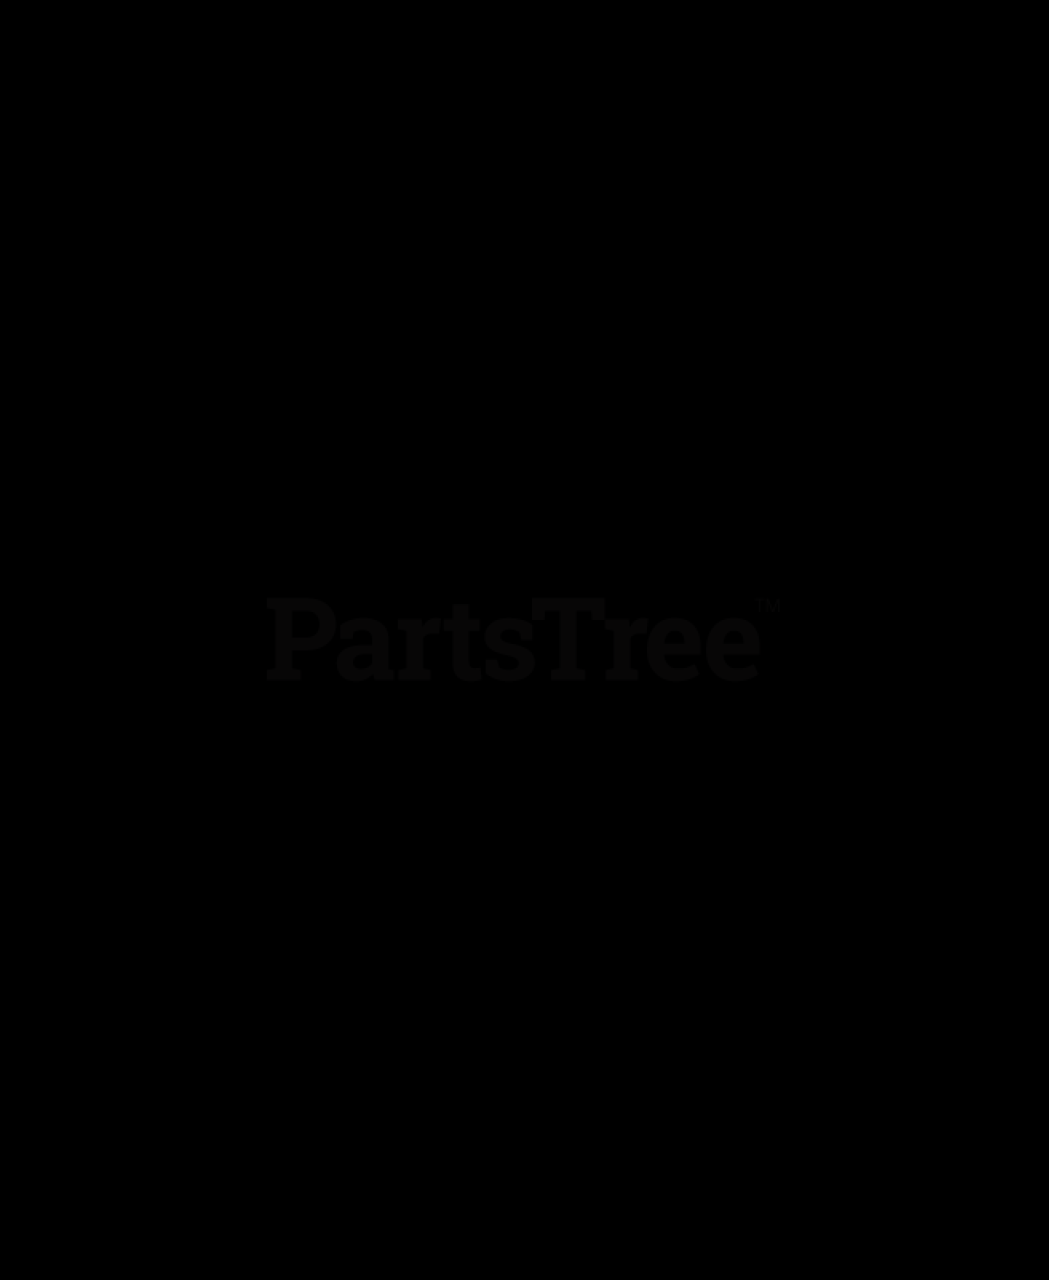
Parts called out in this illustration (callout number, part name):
1	Head, Filter
2	Bolt, Hex .25-20 x .50 Grade 5 Epoxy
3	Filter Element
4	Body, Hydraulic Tank
5	Breather, Dipstick
6	Fitting, Hydraulic, Straight
7	Screw, Tapping .38-16 x .75 Hex Washer Head
8	Fitting, Hydraulic, 90 Degree Elbow
9	Hose, Hydraulic Valve to Tank
10	Hose, Hydraulic, 10-inch
11	Fitting, Hydraulic, 90 Degree Elbow
12	Hose, Hydraulic .50, 5-Inch
13	Fitting, Hydraulic Tee
14	Fitting, Hydraulic (4 F5OLO)
